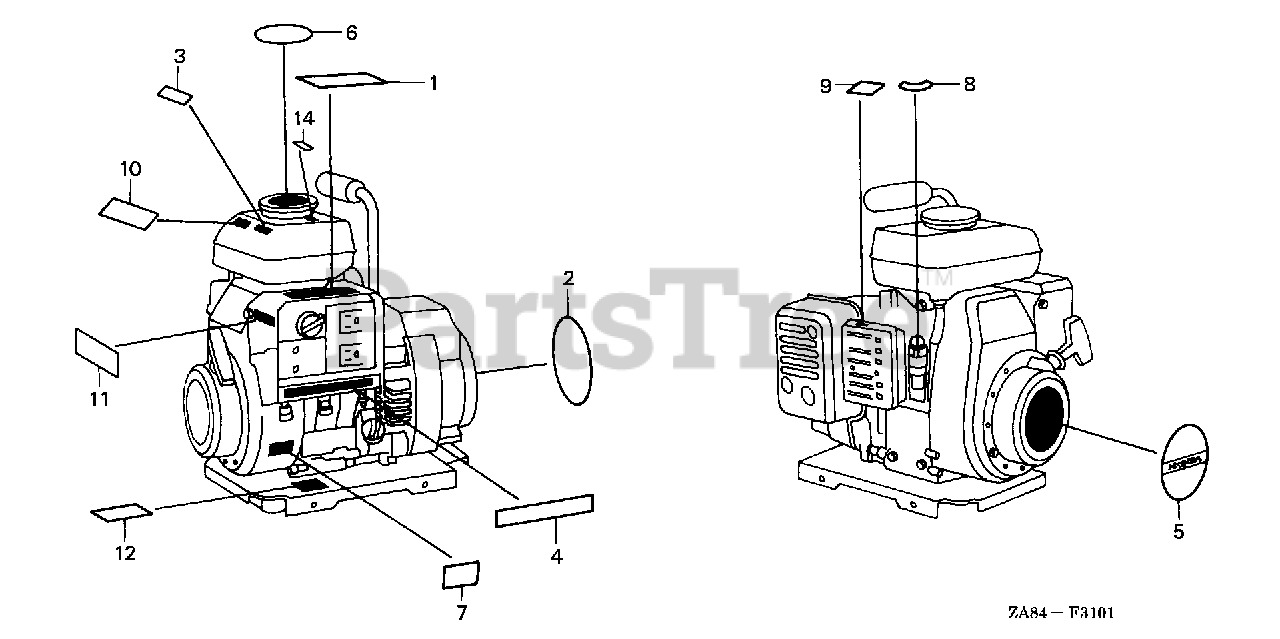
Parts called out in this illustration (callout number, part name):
2	MARK, CAUTION
3	LABEL, RAIN WARNING (ENGLISH)
4	MARK, CONTROL BOX
5	EMBLEM
6	MARK, CAUTION (EXTERNAL)
7	MARK, D.C. CAUTION
8	MARK (EXTERNAL)
9	MARK, CHOKE
10	LABEL, CONNECT WARNING (ENGLISH)
11	MARK, FUEL CAUTION
12	MARK, OIL CAUTION
